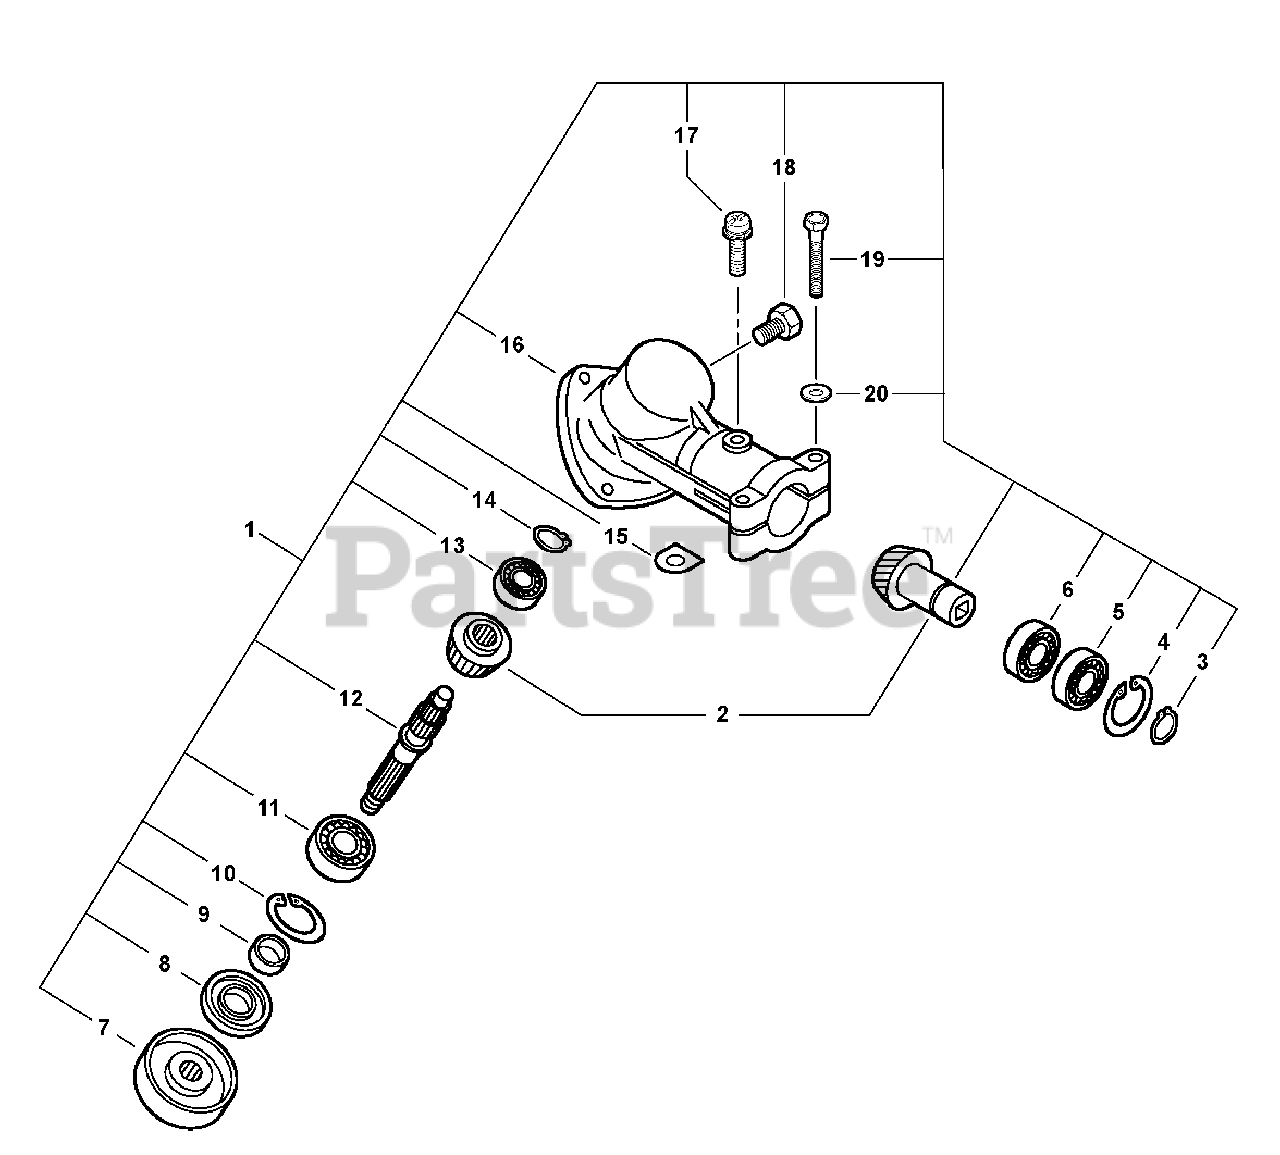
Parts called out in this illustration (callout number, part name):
1	Gear Case Asy
2	Gear Set
3	Circlip 10
4	Circlip 22
5	Bearing, Ball - 6900z
6	Bearing, Ball - 6900
7	Plate, Adapter (Upper)
8	Oil Seal
10	Circlip 32
11	Bearing, Ball - 6201
12	Shaft, p.t.o.
13	Bearing, Ball - 609
14	Circlip 12
15	Washer, Shim
16	Housing, Gear
17	Screw 5x10
18	Bolt 8x8
19	Bolt 5x35
20	Washer 5
